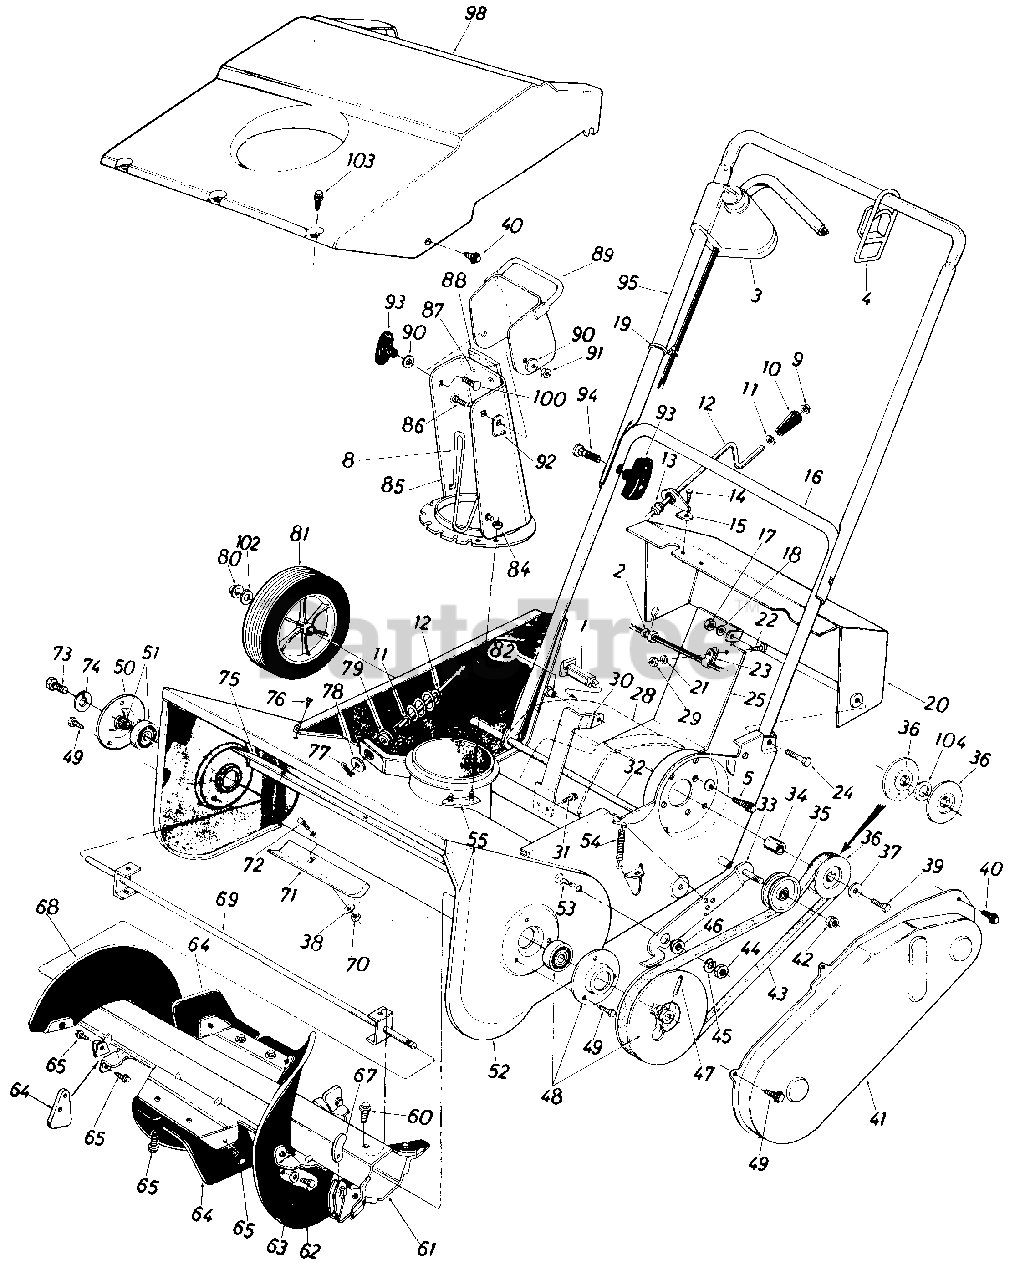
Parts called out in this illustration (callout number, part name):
1	Circuit Breaker 10 Amp
2	Cord Restraint
3	Control with Key
4	Restraint
5	Hex Bolt 5/16-18 x .50" Lg.
8	Chute Guard
9	Push Nut 3/8" Rod
10	Knob Black 3/8" Dia. Hole
11	Fl-Wash. .385" I.D. x .62" O.D.
12	Chute Crank Ass'y.
13	Chute Crank Grommet
14	Hex Tap Scr. 1/4" x .75" Lg.
15	Upper Chute Crank Brkt.
16	Lower Handle
17	Hex Nut 5/16-18 Thd.
18	L-Wash. 5/16" I.D.
19	Cable Tie
20	Dash Panel Ass'y.
22	Truss Mach. Scr. #10-24 x .50" Lg.
23	Cord Restraint
24	Hex Bolt 5/16-18 x 1.50" Lg.
25	Snow Guard
28	Motor Shroud with Hardware
29	Hex Nut #10-24 Thd.
30	Motor Support Brkt.
31	Hex L-Wash. Hd. AB Tap Scr. 1/4 x .62" Lg.
32	Wheel Axle
33	Idler Brake Brkt. Ass'y.
34	Spacer
35	Fl-Idler 2.00" x 1" w/Flange
36	3/8" V-Pulley .625" I.D. x 2.25
37	Bell-Wash. .345" I.D. x .88"
38	L-Wash. 1/4" I.D.
39	Hex Scr. 5/16-24 x .75" Lg.
40	Hex L-Wash. Hd. AB-Tap Scr. 1/4 x .62
42	Hex L-Nut 3/8-24 Thd.
43	V-Belt 1/2" x 34" Lg.
44	Hex Nut 5/16-18 Thd.
45	L-Wash. 5/16" I.D.
46	Shld. Spacer 1.0" O.D. x .315 I.D.
47	Spring Pin Spir. 1/4" Dia. x 1.00" Lg.
48	Kit-Bearing, Cup and Pulley
49	Hex "B"-Tap Scr. 1/4-20 x .38" Lg.
52	Blower Housing Ass'y.
53	Truss Mach. Scr. 5/16-18 x .75" Lg.
54	Extension Spring .33" O.D. x 1.12" Lg.
55	Chute Flange Keeper Ass'y.
60	Hex L-Wash. Hd. AB-Tap Scr. 1/4 x .62" Lg.
61	Auger Half 21.0" Lg.
62	Hex Wash. Hd. Self-Tap Scr. 1/4-20 x .50" Lg.
63	Fl-Wash. .28" I.D. x .74" O.D.
64	Rubber Paddle Half
65	Hex B-Tap Scr. 1/4 x .62" Lg.
67	Small Counterweight
68	8.5" Dia. Rubber Spiral
69	Auger Axle Ass'y.
70	Hex Nut 1/4-20 Thd.*
71	Shave Rail
72	Carriage Bolt 1/4-20 x .75"*
73	Hex Wash. TT-Tap Scr. 1/4-20 x.75" Lg.
74	L-Wash. 1/4" I.D.
75	Thrower Housing Angle
76	Hex "B"-Tap Scr. 114" x .38" Lg.
77	Cotter Pin 3132" Dia. x .75"
78	Fl-Wash. .385" I.D. x 1.5" O.D.
79	Hex Bushing .385" I.D.
80	Cap Speed Nut 1/2" Rod
81	Wheel Ass'y. 6 x 1.50
84	Hex L-Nut 1/4-20 Thd.
85	5.0" Dia. Chute Ass'y.
86	Carriage Bolt 5/16-18 x .62"*
87	Rivet.250" x.44" Lg.
88	Chute Seal
89	Top Chute Ass'y.
90	Bell-Wash. .345" I.D. x .88"
91	Hex Cent. L-Nut 5/16-18 Thd.
92	Top Chute Stop
93	Knob-Handle Ass'y.
94	Curved Hd. Carriage Bolt 5/16-18 x 1.75" Lg.
95	Upper Handle
98	Shroud
100	Carriage Bolt 5/16-18 x 1.00"*
102	Fl-Wash. .75" O.D. x .50" I.D.
103	Hex AB-Tap Scr. #10 x .50"
104	Fl-Wash. .635" I.D. x .93" O.D.
